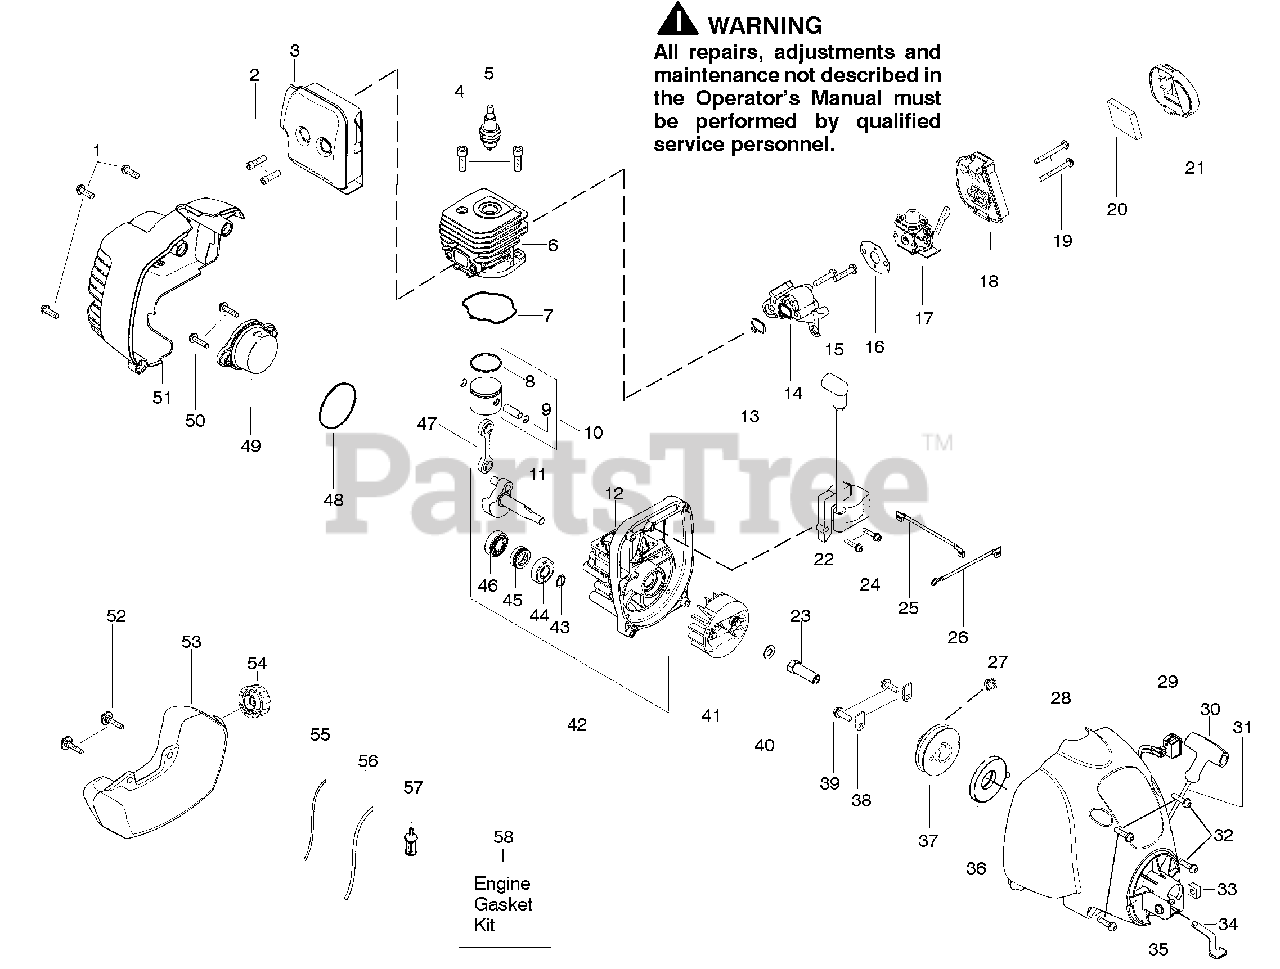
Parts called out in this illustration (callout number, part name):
3	Assy-Muffler/Shield
4	Screw-Cylinder
5	Spark Plug (RCJ 6Y)
7	Seal-Cylinder (kit)
8	Piston Ring
9	Retainer-Piston Pin
10	Kit - Piston
11	Assy-Crankshaft
12	Assy-Crankcase
13	Seal-Cyl/Carb.(kit)
14	Adapter-Carb.
16	Gasket-Carb. (kit)
17	Kit-Carb. Zama (C1U-W18)
17	Kit-Carb. Walbro ( WT-669)
18	Air Box
20	Foam-Air Filter
21	Cover-Air Box
22	Ignition Module
23	Coupling-Drive
25	Assy-Leadwire
26	Assy-Ground Wire
28	Assy.-Fan Hsg
30	Handle-Starter
32	Screw
36	Spring-Starter
37	Kit-Pulley-Starter
38	Retainer-Pulley
41	Assy-Flywheel
42	Assy-C'case & C'shaft
43	Retain. Ring-C'shaft
44	Outer Bearing
46	Inner Bearing
47	Assy-Connecting Rod
48	O-Ring-C'case (kit)
49	Assy-Plug
51	Shroud-Rear Green
51	Shroud-Rear Black
52	Retainer-Tank
53	Assy-Fuel Tank
54	Assy-Fuel Cap
55	Kit-Fuel Line (Small)
56	Kit-Fuel Line (Large)
57	Assy-Fuel Pickup
58	Kit-Engine Gasket
